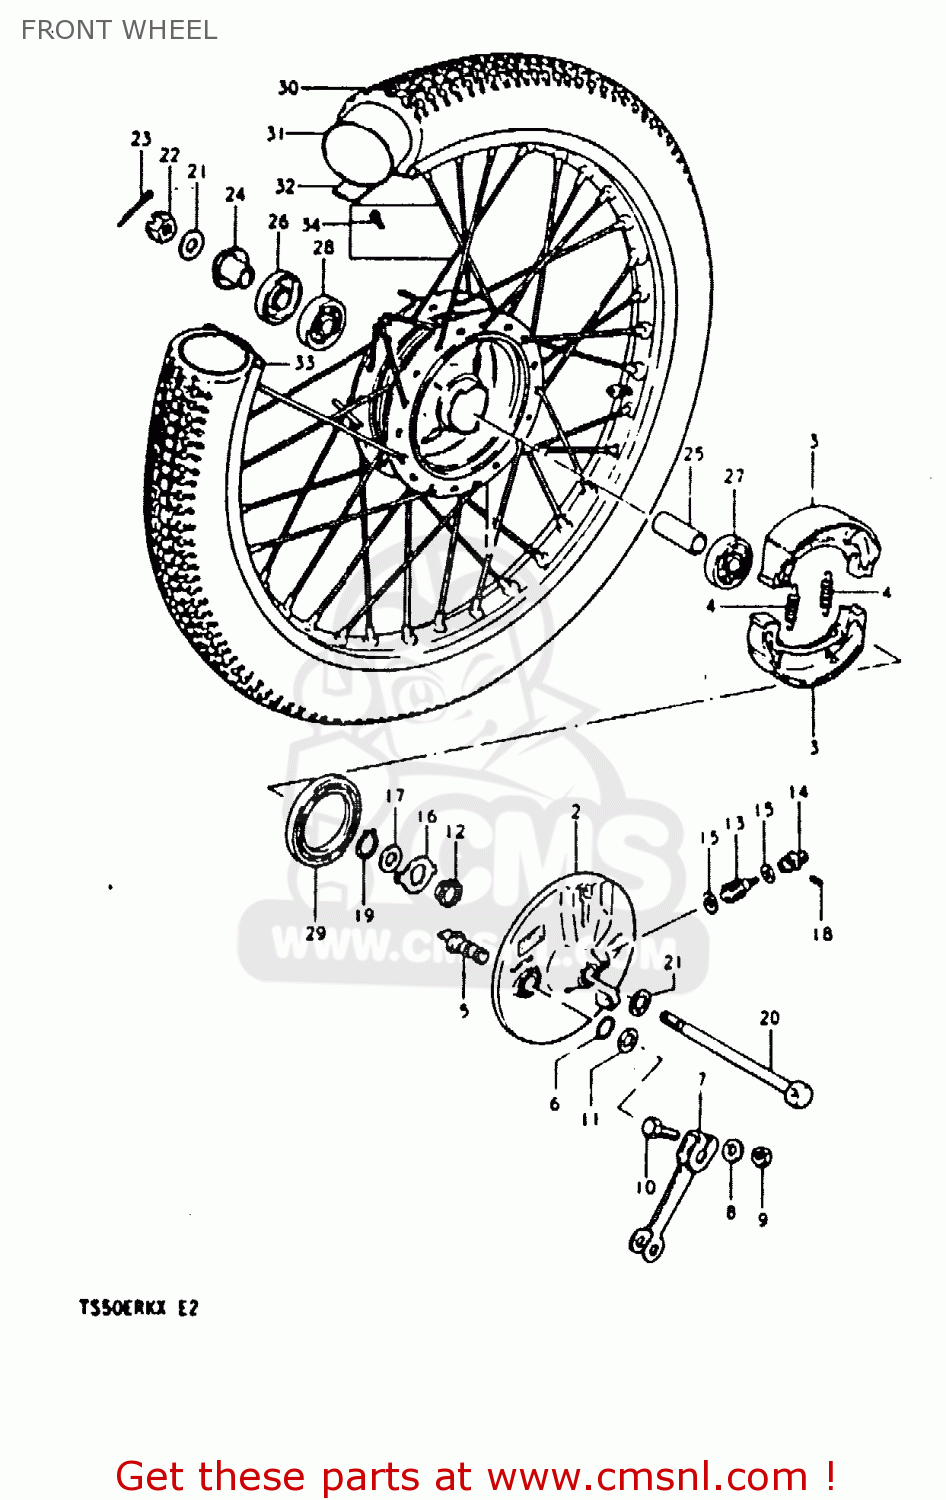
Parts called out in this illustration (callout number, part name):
1	HUB,FRONT
2	PANEL, FRONT HUB
3	SHOE,BRAKE
4	SPRING(L:34)
5	CAM,FRONT BRAKE
6	O-RING (D:2.4 ID:13.8)
7	LEVER,FR BRAKE CAM
8	WASHER
9	NUT
10	BOLT(6X33)
11	WASHER (14.5X22X1.6)
12	GEAR,SPEEDOMETER
13	PINION,SPEEDOMETER
14	BUSH,METER GEAR OUTER
15	WASHER (5.1X9X0.4)
16	DRIVER,SPEEDOMETER GEAR
17	WASHER(18.5X24X1)
18	SCREW
19	CIRCLIP
20	AXLE,FRONT
21	WASHER
22	NUT
23	PIN 20X20
24	SPACER,FRONT AXLE,RIGHT
25	SPACER (10.2X16X51)
26	SEAL,OIL(15X31X5)
27	BEARING
28	BEARING
29	OIL SEAL (43X58X7)
30	TIRE,FRONT
31	TUBE
32	PROTECTOR,WHEEL,INNER
33	RIM, WHEEL
34	SPOKE ASSY
